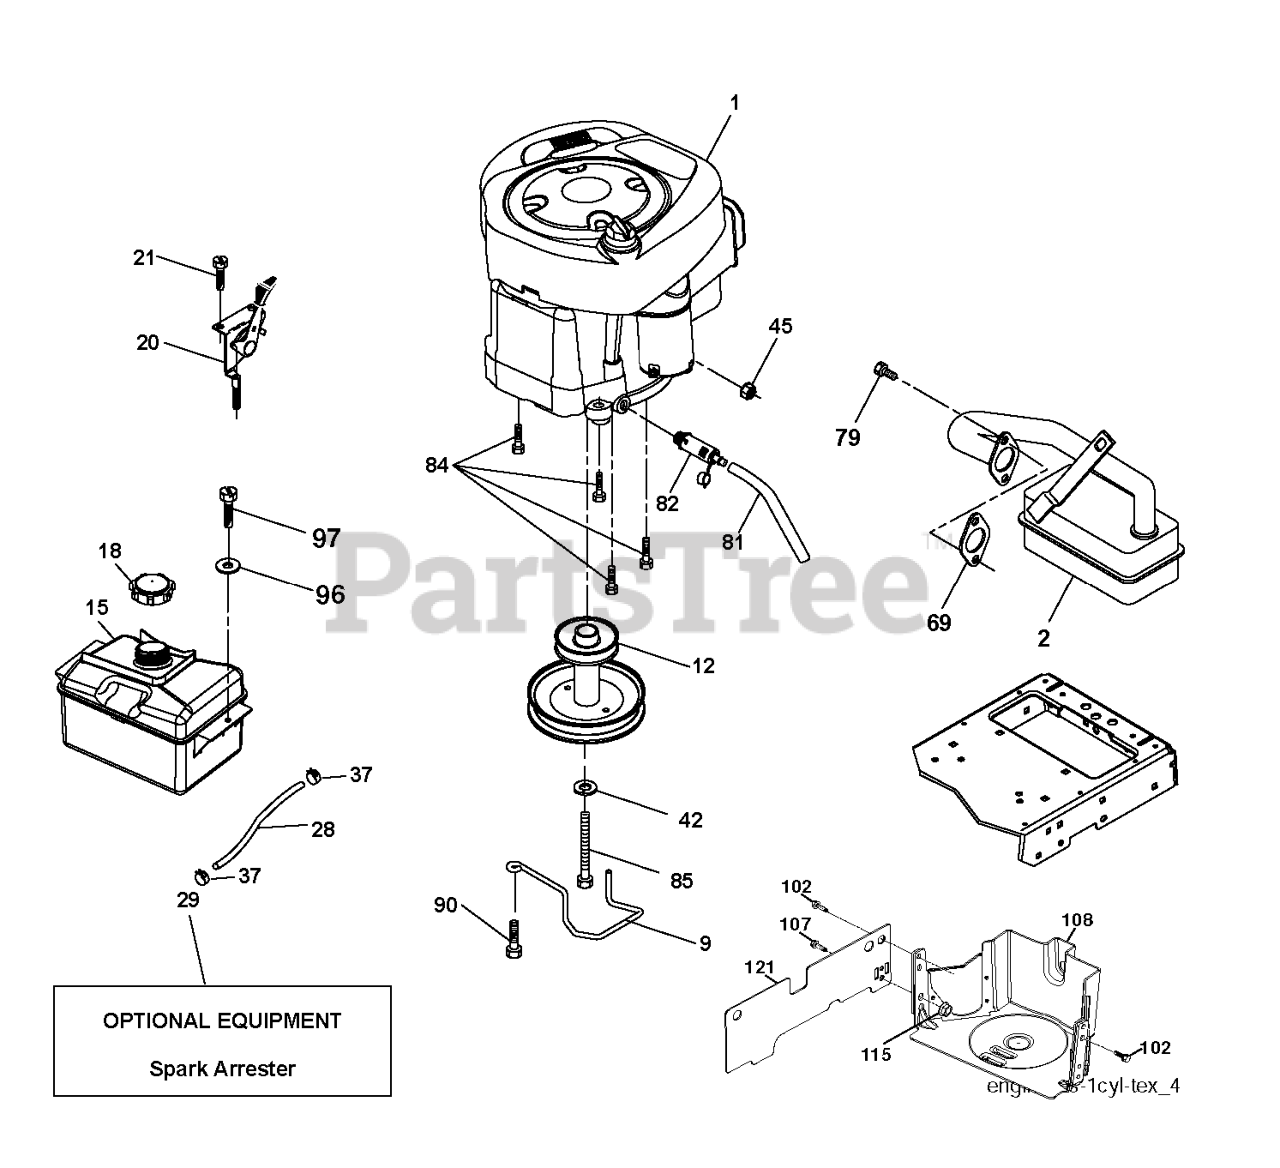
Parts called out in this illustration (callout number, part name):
2	MUFFLER.B&S.MODEL.21.11HP.OHV
9	KEEPER.BELT.ENGINE.3.25 (3 2)
12	PULLEY.ENG.CL.MECH.SLVR.LT/YT
15	RP TANK FUEL FRT 1.5 GAL
18	FUEL CAP
20	CONTROL.TH/CK.C.
21	SCREW.#10 X 0.750.BOS
28	LINE.FUEL.20
29	KIT.SPARK ARRESTOR 794945 B&S
37	HOSE CLAMP
42	LOCKWASHER
45	NUT
69	REPL BY 532 27 22-93
79	SCREW.SOCKET HD.5/16-1
81	TUBE, DRAIN OIL ASM.
82	PLUG DRAIN OIL EASY
84	SCREW.3/8-16
85	BOLT HEX 7/16-20X4-1/4"
90	SCREW 3/8-16X1
97	SCREW HEXWSHR 1/4-20X3/4
102	SCREW
107	SCREW.1/4-20X5/8
108	COVER PULLEY
115	PALNUT 1/4
121	SHIELD LEFT
